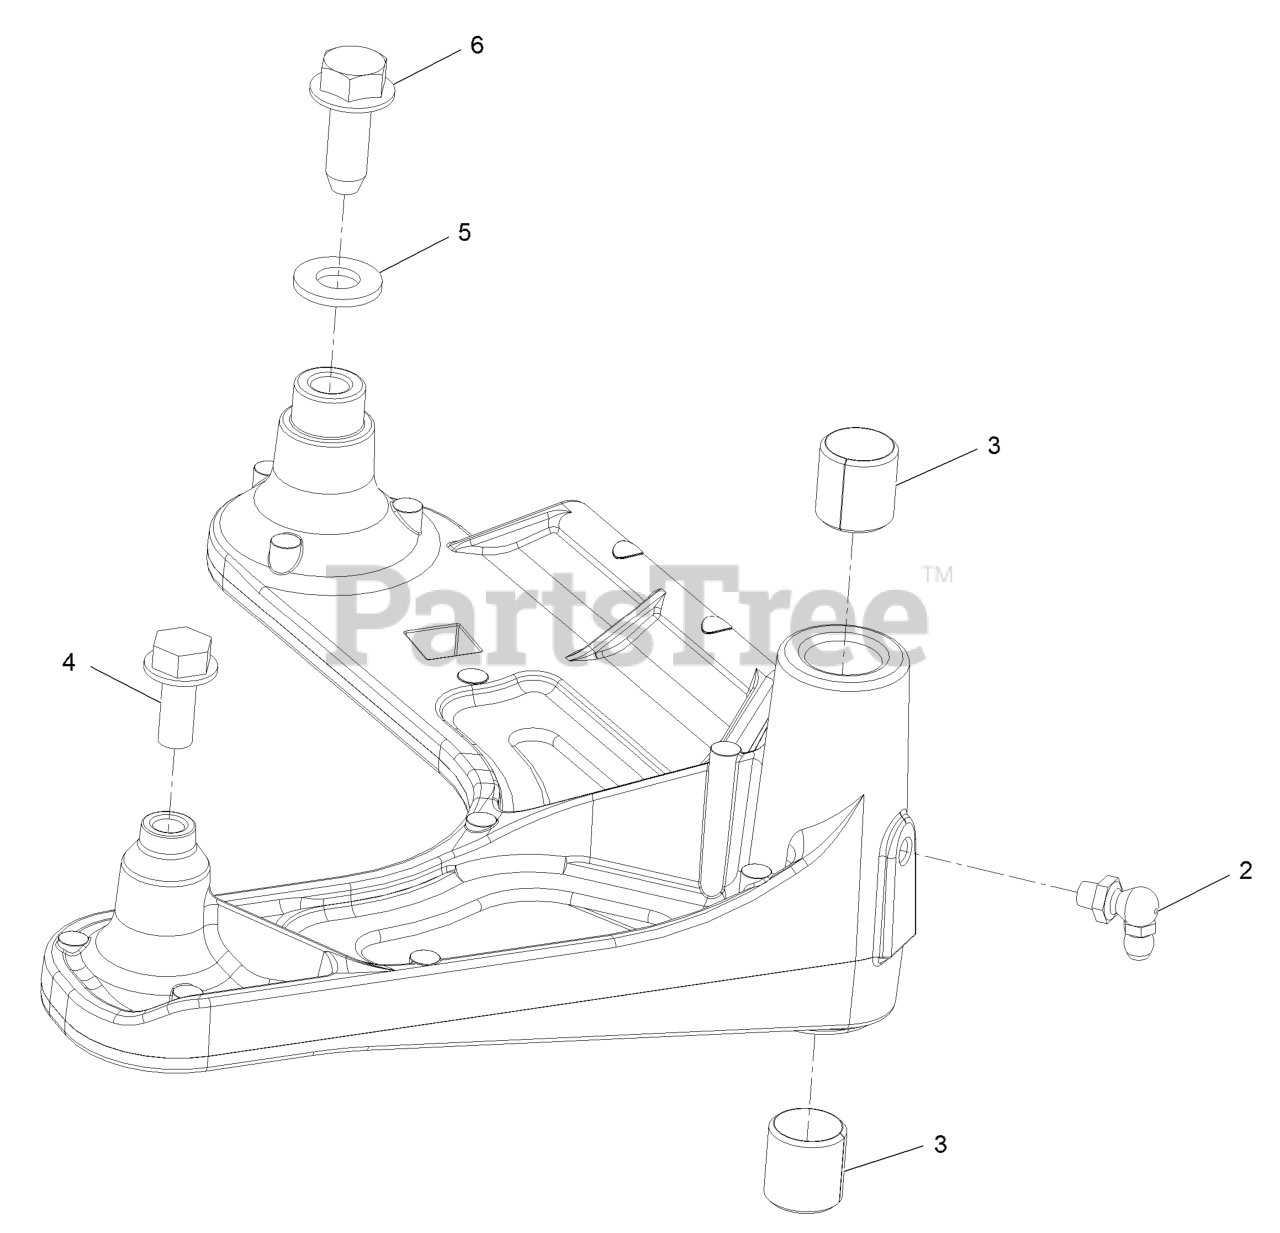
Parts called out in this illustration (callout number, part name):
2	FITTING-GREASE, 90 DEG
3	SLEEVE-BEARING
4	SCREW-THD ROLL, HWH
5	WASHER-FLAT
6	SCREW-FORMING, THREAD
